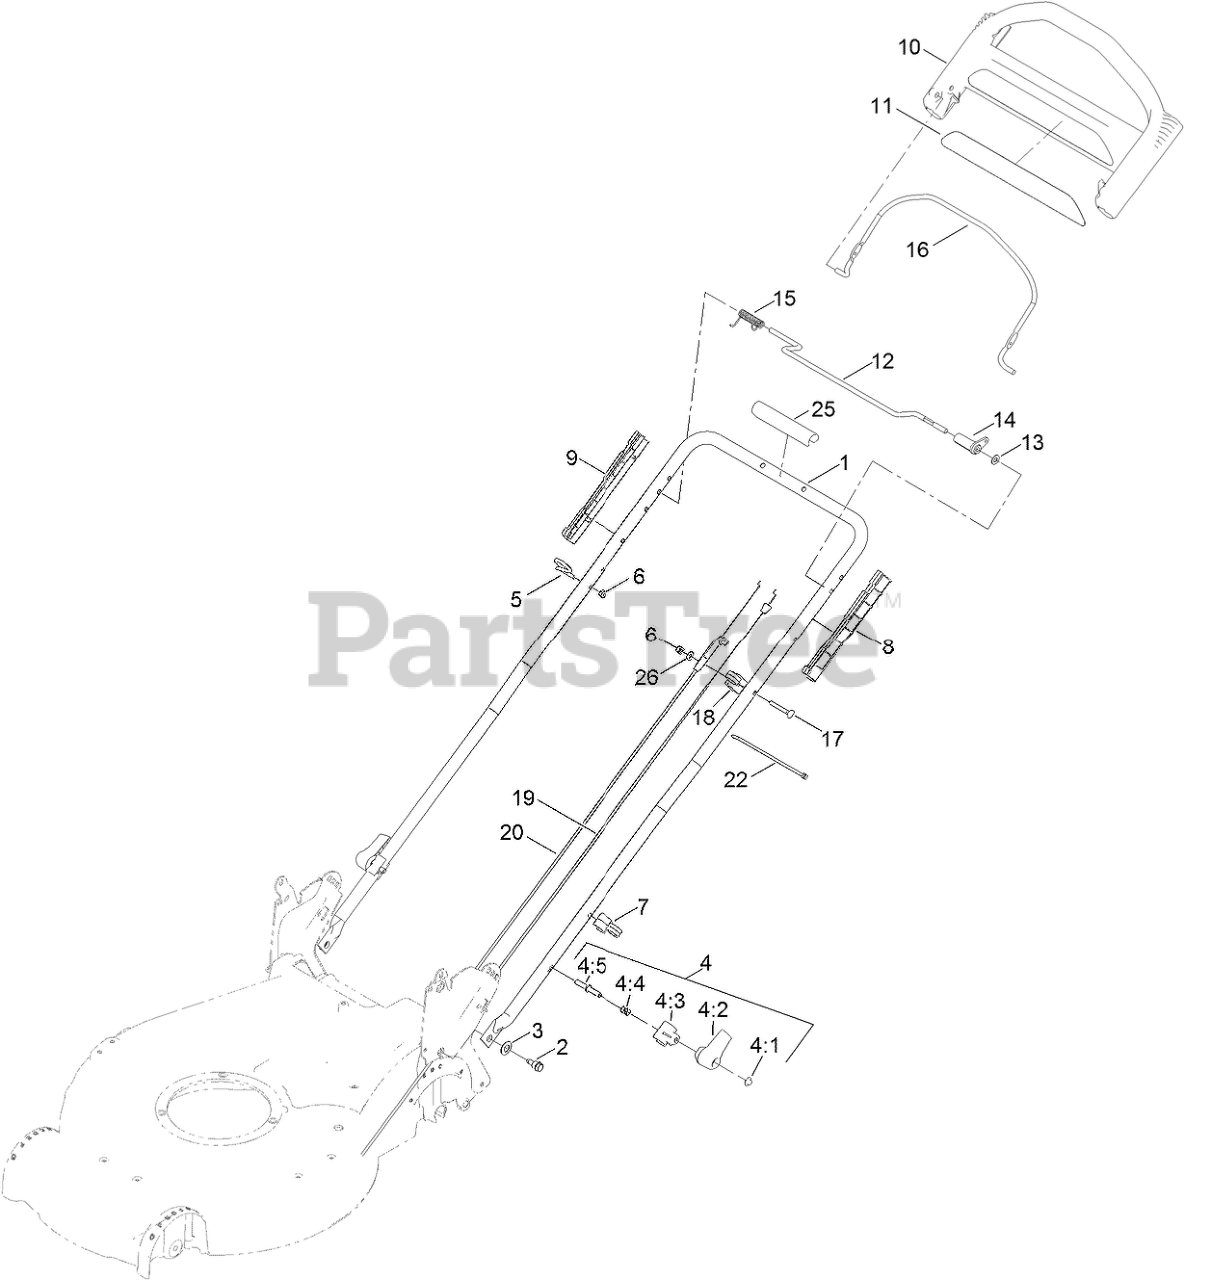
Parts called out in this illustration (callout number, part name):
2	BOLT-SHOULDER
3	WASHER-SPRING, CONICAL
4	QUICK RELEASE ASM
4:1	NUT-PUSH
4:2	LEVER-RELEASE
4:3	ANCHOR-SPRING
4:4	SPRING-COMPRESSION
4:5	ROD-RELEASE
5	GUIDE-ROPE
6	NUT-HEX
7	GUIDE-CABLE
8	GUIDE-LH
9	GUIDE-RH
10	HANDLE-CONTROL
11	DECAL-HANDLE
12	BAR-CONTROL, TRACTION
13	WASHER-PLAIN
14	LEVER-TRACTION
15	SPRING-TORSION
16	BAIL-BRAKE
17	BOLT-CARR
18	ANCHOR-CABLE
19	CABLE-TRACTION
20	CABLE-BRAKE
22	TIE-CABLE
25	HANDLE-COVER
26	WASHER-FLAT
